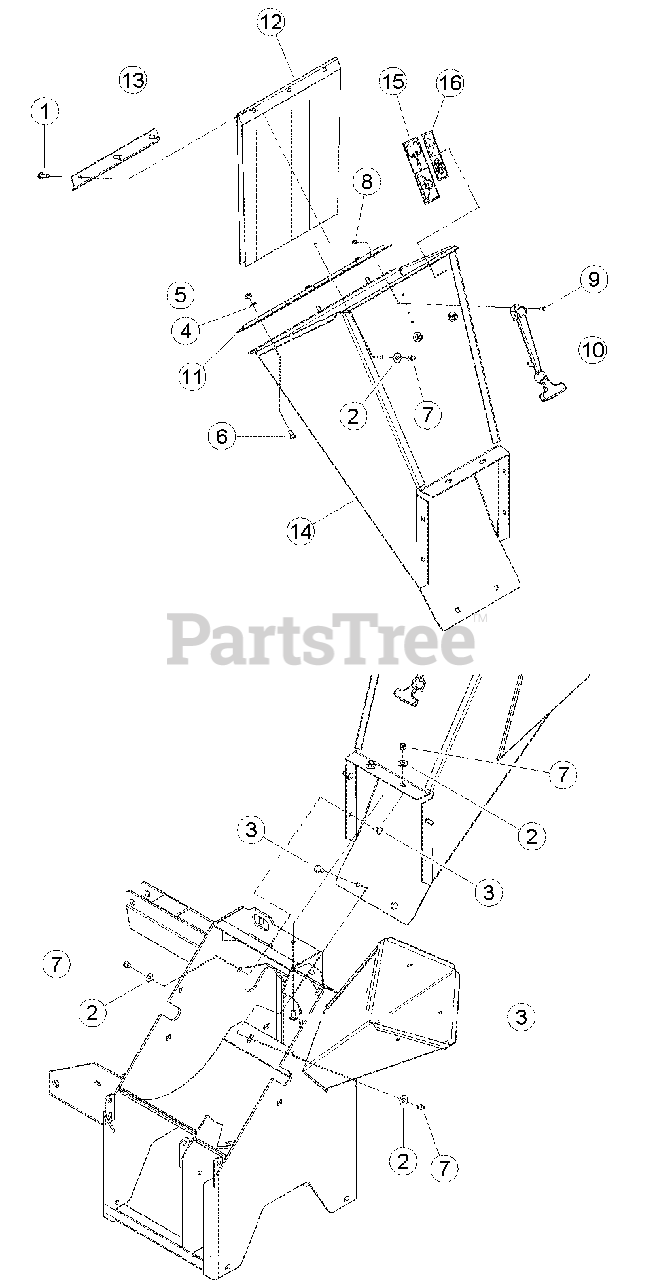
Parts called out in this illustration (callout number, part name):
1	BOLT, 3/8 X 1 HEX HD GR5 ZP
2	WASHER, 3/8 FLAT ZP
3	BOLT, 3/8 X 1 CRG NC ZP
4	WASHER, 5/16 FLAT ZP
5	NUT, 5/16 NE NYLOCK ZP
6	BOLT, 5/16 X 3/4 CRG GR5 NC ZP
7	NUT, 3/8 NE NYLOCK ZP
8	NUT, 10/24 NYLOCK TYPE NM, ZP
9	SCREW, MCH 10-24 X 1/2 PAN HD,PH ZP
10	LATCH, FLEXABLE DRAW W/ KEEPER
11	HINGE, EXTENSION TRAY
12	FLAP, C/S CHUTE
13	ANGLE, FLAP ANCHOR
14	ASSEMBLY, SHREDDER CHUTE SERVICE PART
15	DECAL, BLADE DANGER ISO
16	DECAL, SHREDDER SIZE ISO
